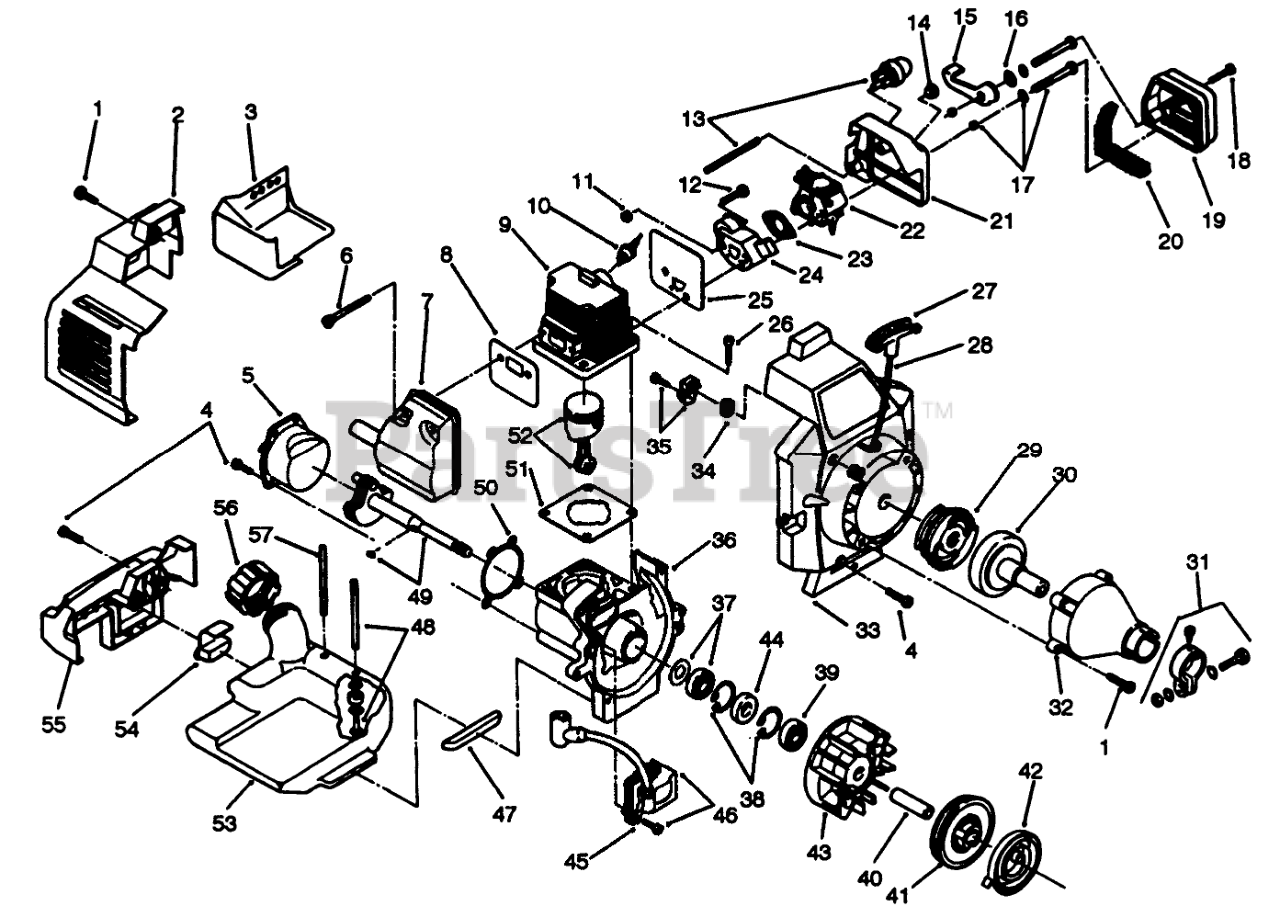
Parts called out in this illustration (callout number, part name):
1	CLUTCH COVER SCREW ASM
2	REAR COVER
3	HEAT SHIELD
4	MOUNTING SCREW SET
5	Cap-Crankcase (Incl. Ref. No.4)
6	MUFFLER MOUNTING SCREWS
7	Assembly-Muffler (Incl. Ref. No. 8)
8	MUFFLER GASKET
9	Cylinder (Incl. Ref. No. 51)
10	SPARK PLUG
11	SPACER NUT SET
12	SPACER SCREW SET
13	PRIMER & HOSE ASM
14	SWITCH PLUG
15	CHOKE LEVER
16	WAVEY WASHER
17	CARB MOUNTING ASM
18	Screw
19	AIR CLEANER COVER
20	FOAM AIR FILTER ELEMENT
21	Air Cleaner Base Asm.
22	Assembly-Carburetor (Incl. Ref. No.23)
23	CARB.GASKET(PK.10=1)
24	Assembly-Spacer, Carb. (Incl. Ref. No. 11 & 12)
25	CYL/CARB SPACER GASKET
26	SCREW
27	Handle-Pull
29	Clutch Rotor Asm.
30	CLUTCH DRUM ASM
31	CLAMP ASM - UPPER
32	Assembly-Housing, Clutch (Incl. Ref. No. 1)
33	Assembly-Housing (Incl. Ref. No. 4)
34	ROPE GUIDE
35	PULLEY RETAINER ASM
36	Assembly-Crankcase (Incl. Ref. No.5, 37-39, 44, & 49-50)
37	INNER BEARING ASM
38	Snap ring
39	OUTER BEARING
40	SPACER
41	RECOIL PULLEY
42	RECOIL SPRING
43	Assembly-Flvwheel
45	GROUND TAB
46	MODULE ASM
47	FRONT FUEL TANK PAD
48	FUEL LINE ASM
49	POWER SHAFT ASM
50	CRANKCASE CAP GASKET
51	CYLINDER GASKET
52	PISTON & ROD ASM
53	FUEL TANK ASM
54	REAR FUEL TANK PAD
55	FUEL TANK BRACKET
56	FUEL TANK CAP
57	FUEL RETURN LINE
